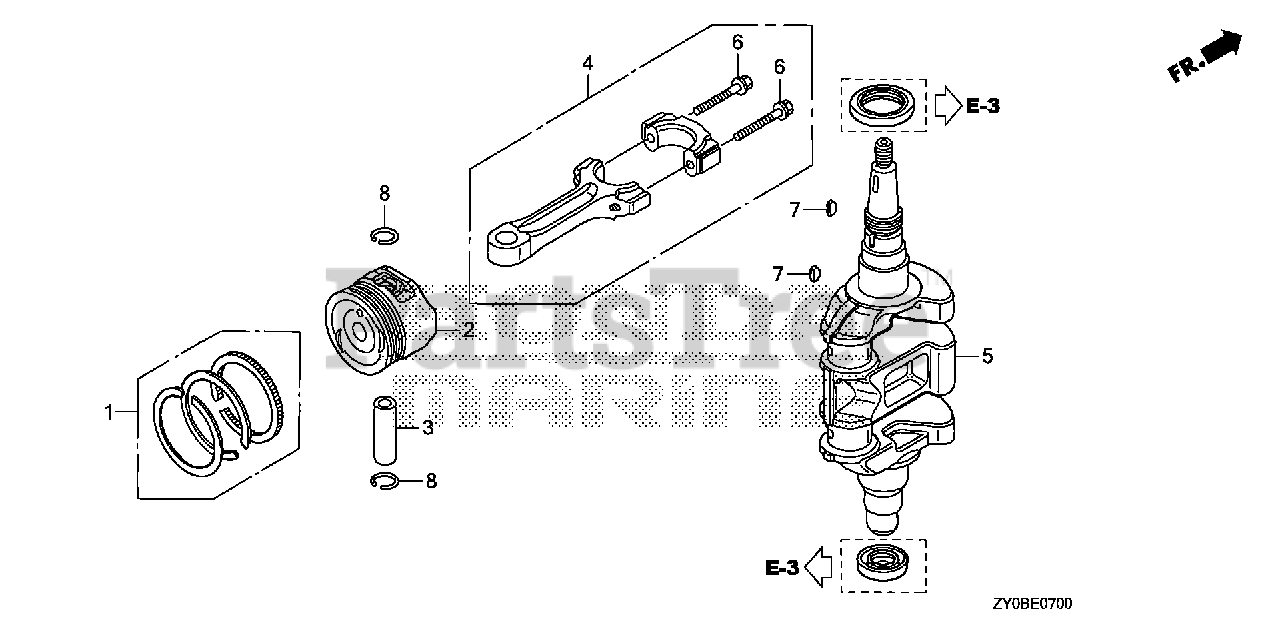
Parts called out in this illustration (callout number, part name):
1	RING SET, PISTON
3	PIN, PISTON
4	ROD, CONNECTING
5	CRANKSHAFT
6	BOLT, CONNECTING ROD (6X34)
7	KEY, SPECIAL (16X13)
8	CLIP, PISTON PIN (16MM)
